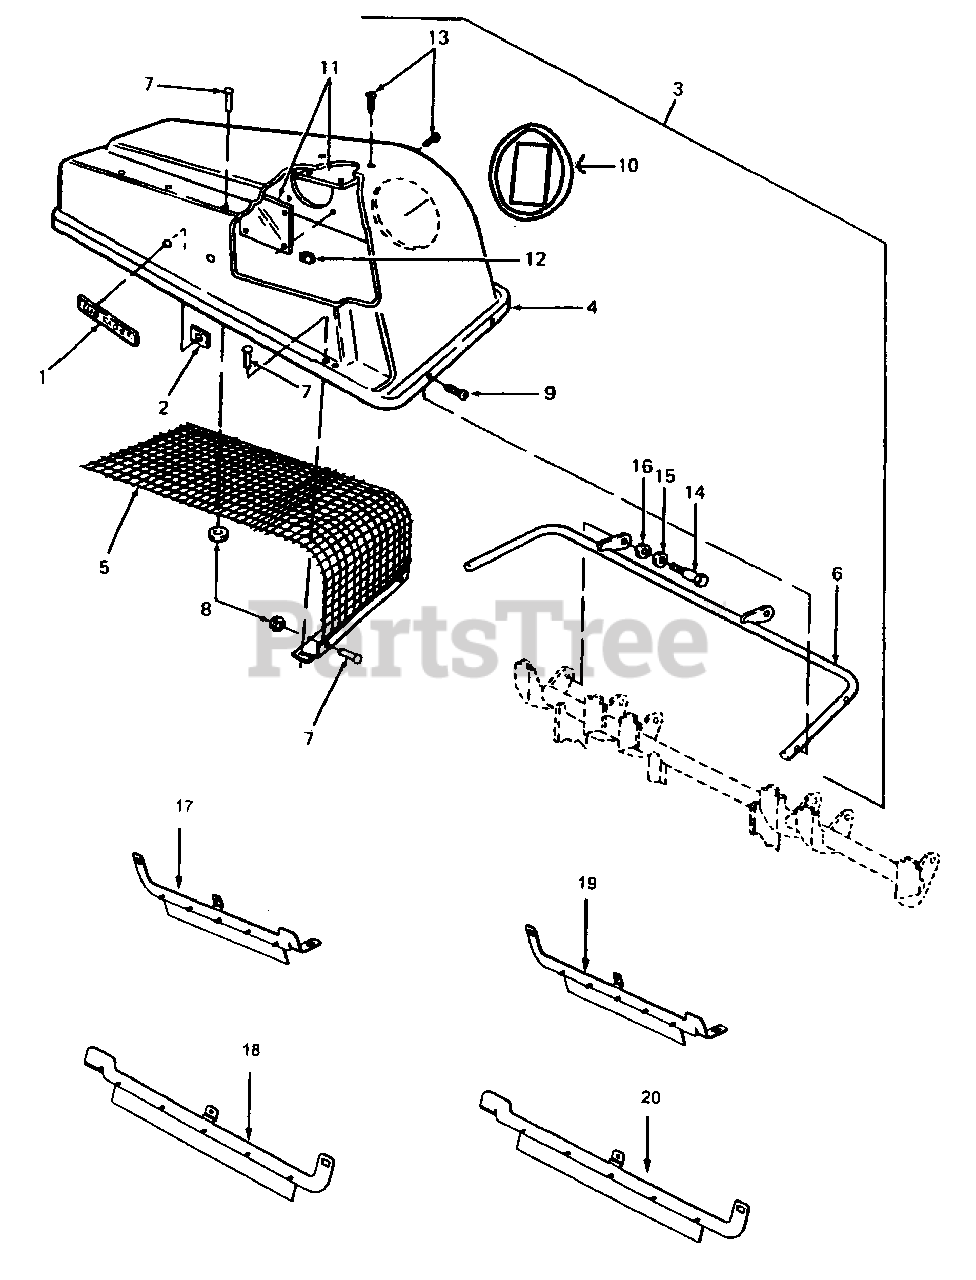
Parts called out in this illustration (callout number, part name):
1	Plaque, Logo w/Studs
2	Nut, Push-on Speed
3	Cover Assy, Grass Catcher
8	Washer, Flat, .218 X .62 X .063
9	Screw, Hex Washer. 1/4 X .50 Lg.
10	Seal, Tube
11	Plate, Plastic, 1/8 Thk X 5.62 Sq.
12	Nut, U-Type Speed
13	Screw, Truss Mach., #10 X .50 Lg.
14	Screw, Shld.
15	Washer, Flat, .510 X.75 X .033
16	Washer, Bell, .515 X 1.14
17	Brkt. Assy-w/Flapp RH 48"
18	Brkt. Assy-w/Flapp LH 48"
19	Brkt. Assy-w/Flapp RH 54"
20	Brkt. Assy-w/Flapp LH 54"
